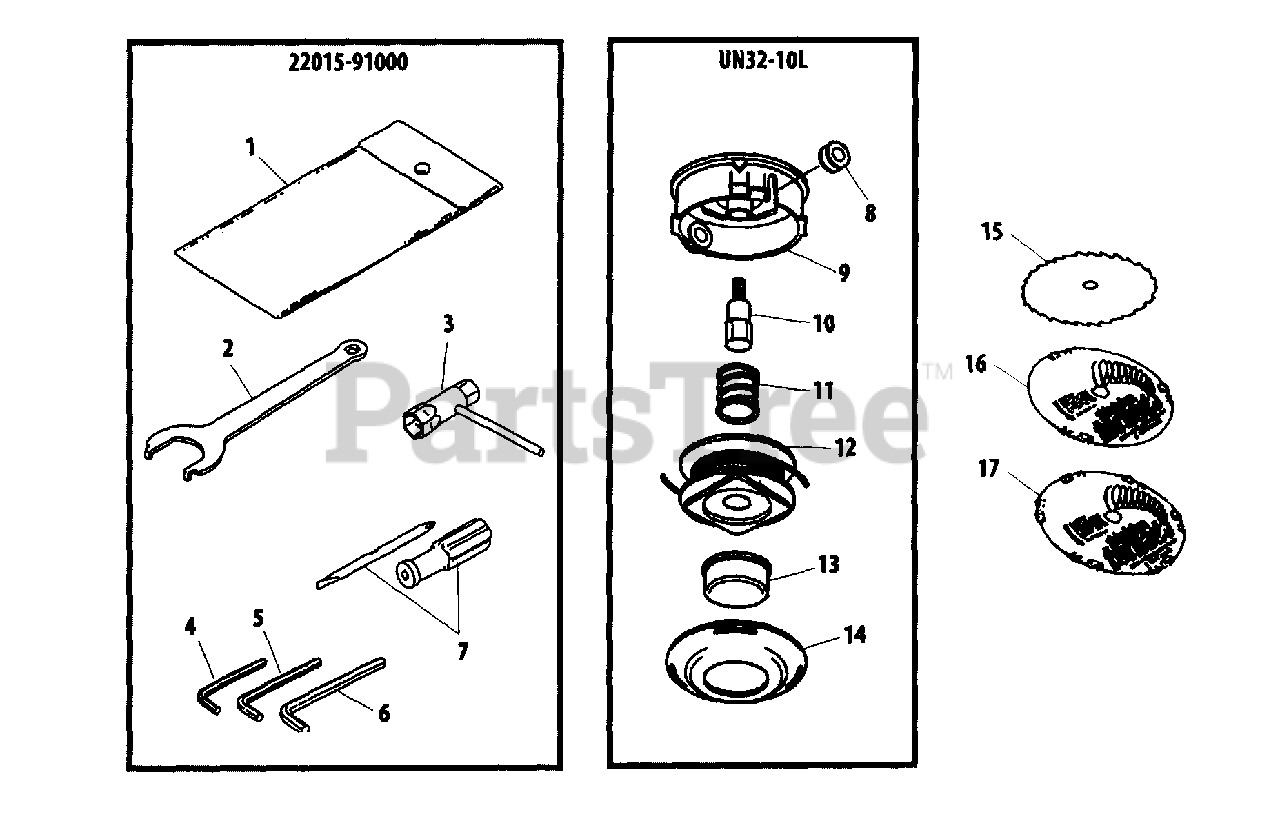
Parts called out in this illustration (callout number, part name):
1	BAG, TOOL
2	SPANNER
3	T-WRENCH - 17X19mm
4	HEX KEY - 4mm
5	HEX KEY - 6mm
6	HEX KEY - 3mm
7	SCREWDRIVER
10	SHAFT BOLT 10MM LH
15	BLADE - 30 TOOTH -- 9" (22cm)
16	BLADE - 6 TOOTH -- 9" (22cm)
17	BLADE - 12 TOOTH -- 9" (22cm)
22015-91000	TOOL KIT
UN32-10L	TRIMMER HEAD ASSY
